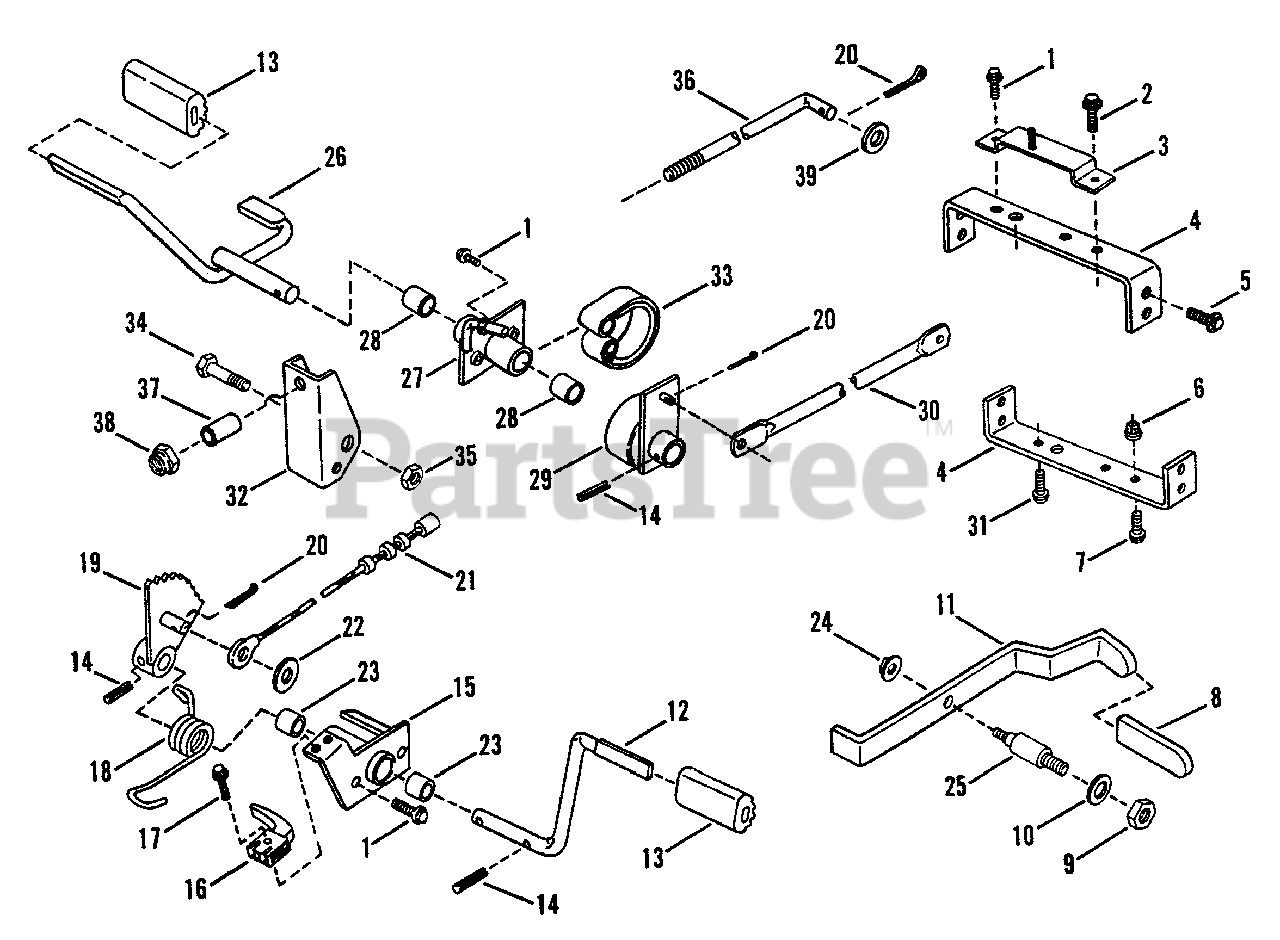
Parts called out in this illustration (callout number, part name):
1	SCREW, 5/16-18 x 5/8" Hex Head Self-Tap
2	SCREW, 5/16-18 x 1" Hex Flange Lock
3	BRACKET ASSEMBLY
4	STRAP, Cross
5	SCREW, 3/8-16 x 1/2" Hex Washer Self-Tapping
6	NUT, 3/8-16 Hex Flange
7	SCREW, 3/8-16 x 1-3/4" Hex Flange Lock
8	SLEEVE, Parking Brake
9	NUT, 3/8-16 Hex
10	WASHER, 3/8 Int. Tooth Lock
11	LEVER, Parking Brake
12	PEDAL, Neutral Brake
13	PAD, Pedal
14	PIN, 3/16" x 1-1/4" Roll
15	BRACKET, Pedal Pivot
16	SWITCH, Neutral Brake Interlock
17	SCREW, #10-24 x 1" Self-Tap
18	SPRING, Neutral Brake
19	ARM, Neutral Brake
20	PIN, 3/32 x 3/4" Cotter
21	CABLE, Neutral Brake
22	WASHER, 3/8" Flat
23	BEARING, Sleeve
24	NUT, 1/4-20 Hex
25	STUD, Parking Brake
26	WELDMENT, Control Pedal
27	ASY, Control Panel Pivot
28	BEARING, Dx
29	WELDMENT, Pedal Arm
30	ROD, Speed Control
31	BOLT, 3/8-16 x 1" Hex Fl. Lock
32	LEVER, Friction Ctrl
33	BAND, Brake Assembly
34	SCREW, 1/4-28 x 2" Hex Head Cap, Grade 5
35	NUT, 1/4-28 Hex Top Lock
36	BRAKE ROD
37	SPACER
38	NUT, 5/16-18 Hex Nyloc
39	WASHER, 5/16" x 1-1/4" x 3/32" Flat
